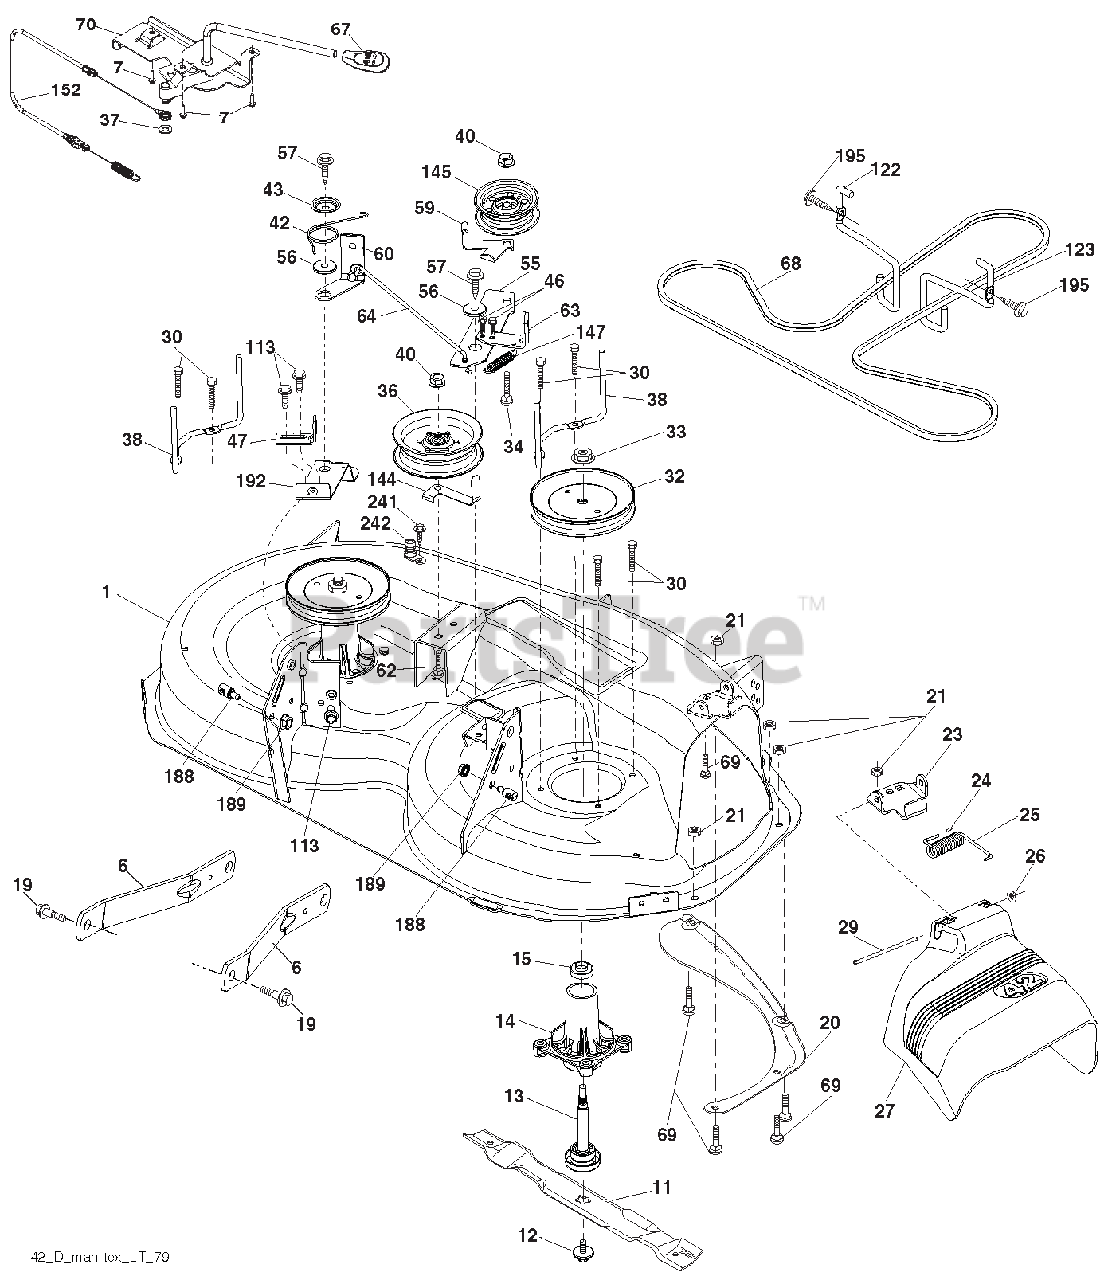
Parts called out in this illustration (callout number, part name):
1	DECK.WELDMENT.42"N/GWB
6	ARM.SUSPENSION.MOWER.REAR.LD
11	BLADE.MOWER.42"HI LIFT PREMIUM
12	SCREW 7/16-20 X 1
13	SHAFT ASM
14	HOUSING.MANDREL.4PT.SERVICE
15	BEARING
19	BOLT.SHOULDER
20	BAFFLE.VORTEX.42.STD/HEAVY DTY
21	Nut, Hex, Crownlock 5/16-18
23	BRACKET.DEFLECTOR.38/42"2005
24	CAP.SLEEVE..80X.112.BLK.MOWER
25	SPRING.TORSION.DFL.38/42/46.GR
26	NUT.PUSH.PHOS.& OIL
27	SHIELD.DEFLECTOR.
29	ROD.HINGE.42/46"
30	SCREW.THD ROLL.DOD PT.HEX
32	PULLEY.MANDREL.5.438 PD.42"
32	MANDREL ASM
33	NUT.FLANGE.LOCK.TOP
34	BOLT.CARR.SH.3/8-16X1-1/2.GR5
36	PULLEY.IDLER.4.50.RAW
37	WASHER.13/32 X 13/16 X 16 GA.
38	KEEPER.BELT.MANDREL.PULLEY
40	Nut, Hex, Flangelock 3/8-16
42	SPRING.TORSION.BRAKE
43	SPRING.TORSION.RETAINER
46	SCREW.THD.ROLL.1/4-20 X 5/8
47	BRACKET.CLUTCH.CABLE
55	IDLER.ARM
56	SPACER.RETAINER
57	SCREW.3/8-16X1.SMGML.TAP/R.BLK
59	GUARD.TUV.IDLER
60	ARM.BRAKE.MOWER.42"
62	BOLT.RD.HD.SQ.NK.3/8-16UNC X 2
63	ARM.BRAKE.MOWER
64	LINKAGE.BRAKE
67	HANDLE.CLUTCH.CABLE.LT TEX.428
68	BELT.DRIVE.100.97"
69	BOLT.RDHD.SQNK.5/16-18 X 5/8
70	CABLE.CLUTCH.MANUAL
113	BOLT.5/16-18HEX.WHS.HD.LCKSERR
116	BOLD SHLD "A" 2.41 "B" 1.66
117	WHEEL.GAGE.HALF.SPOKED
119	Washer 3/8 x 7/8 x 14 Ga.
122	KEEPER.BELT.ENGINE.LH.LT.TEX
123	KEEPER.BELT.ENGINE.RH.LT.TEX
144	KEEPER.BELT.MOWER
145	PULLEY.IDLER 48"PRIMARY
147	SPRING.RETURN
152	CLUTCH ASM.
188	STUD.FASTNER.W/'D'ANTI-ROTATIO
189	Nut, Lock Hex Flange 5/16-18 u
192	BRACKET.BRAKE.STAND.LH
195	SCREW.HEXWSH THDR3/8-16X3/4.BL
242	PORT WASHOUT
